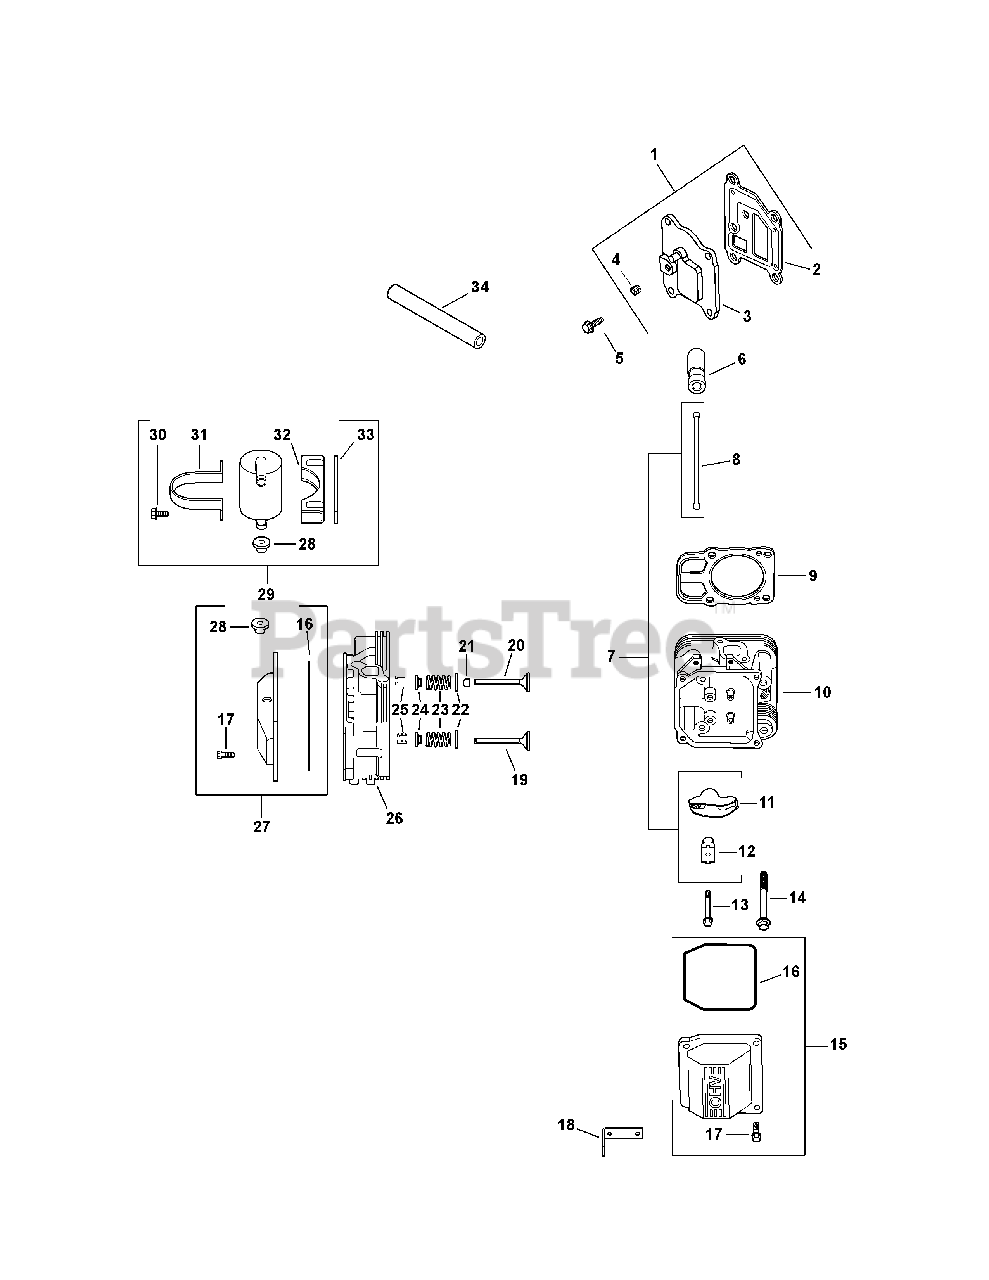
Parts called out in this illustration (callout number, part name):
1	KIT, BREATHER COVER W/GASKET
2	GASKET, BREATHER
3	KIT, BREATHER COVER
4	PLUG, CTSK PIPE 1/8''
5	SCREW, FLG THD FRM M6X1.0X20
6	LIFTER, VALVE HYDRAULIC
7	KIT, VALVE TRAIN
9	KIT, CYL HEAD GASKET(C730-745)
10	KIT, CYLINDER HEAD #2
12	PIVOT, ROCKER ARM
13	SCREW,FLG M10X1.5X90
14	SCREW, FLG M6X1.0X34
15	KIT, VALVE COVER-PLAIN
16	O-RING, VALVE COVER
17	SCREW, FLG M6X1.0X30
18	STRAP, LIFTING
19	VALVE, EXHAUST (STD)
19	VALVE, EXHAUST (.25)
20	VALVE, INTAKE (STD)
20	VALVE, INTAKE (.25)
21	SEAL, VALVE STEM
22	RETAINER, SPRING
23	SPRING, VALVE
24	CAP, VALVE SPRING
25	KIT, RETAINER
26	KIT, CYLINDER HEAD #1
27	KIT, VALVE COVER
28	GROMMET, RUBBER
29	KIT, BREATHER SEPARATOR
30	SCREW, FLG THD FRM M5X0.8X16
31	STRAP, BREATHER
32	BRACKET, BREATHER SEPARATOR
34	HOSE
